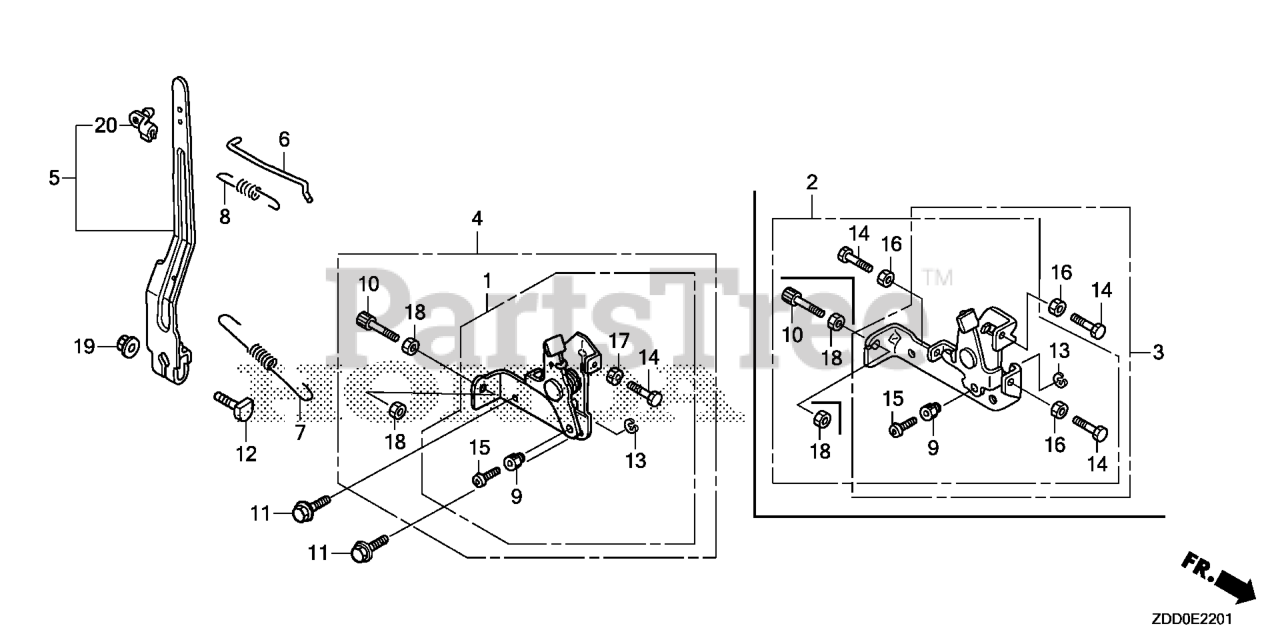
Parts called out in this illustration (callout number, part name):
4	CONTROL ASSY.
5	ARM, GOVERNOR
6	ROD, GOVERNOR
7	SPRING, GOVERNOR
8	SPRING, THROTTLE RETURN
9	HOLDER, WIRE
10	BOLT, CABLE ADJUSTING (6X34)
11	BOLT, FLANGE (6X14)
12	BOLT, GOVERNOR ARM
13	CIRCLIP (5MM) Use from Engine SN 2327377.
14	BOLT, HEX. (5X20)
15	SCREW, PAN (4X6)
17	NUT, HEX. (5MM)
18	NUT, HEX. (6MM)
19	NUT, FLANGE (6MM)
20	JOINT, ROD
